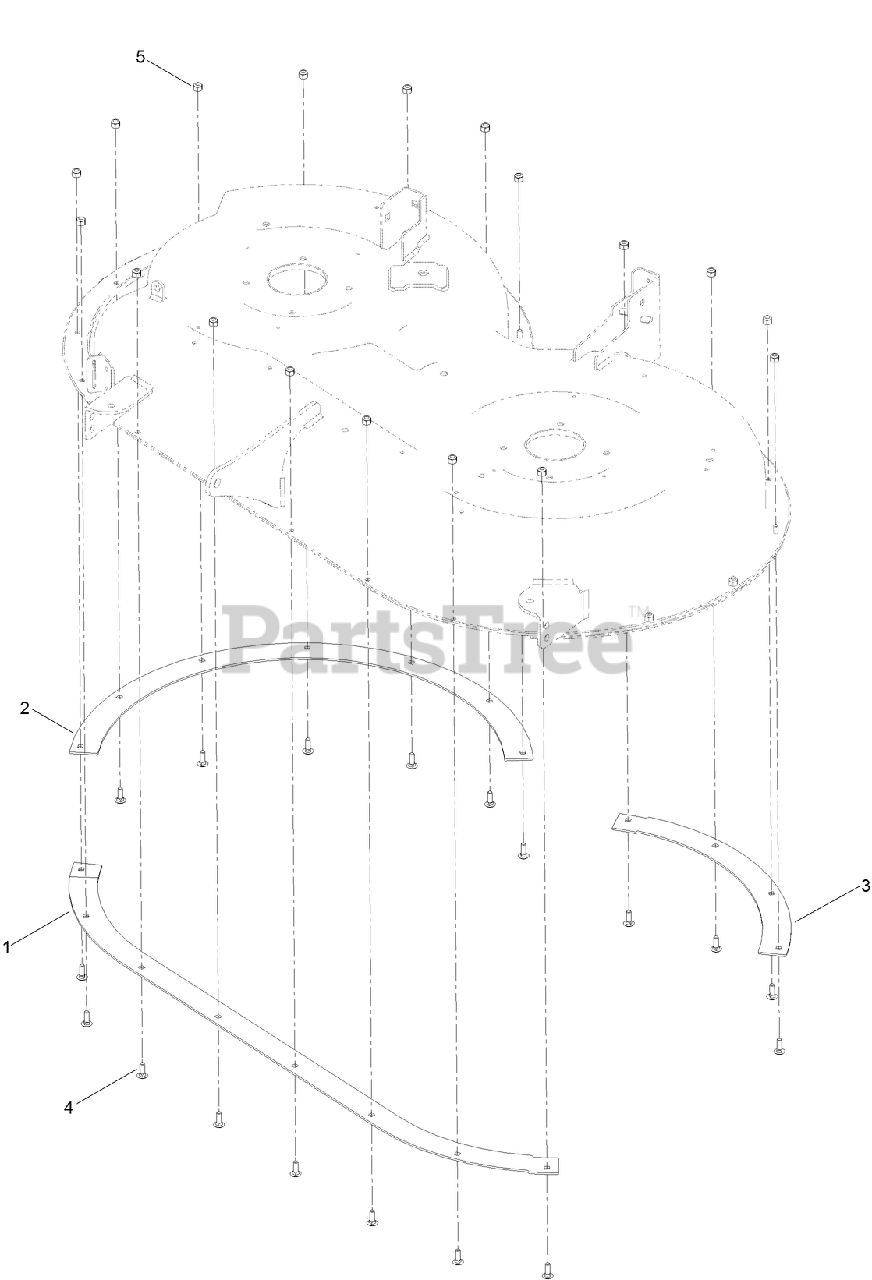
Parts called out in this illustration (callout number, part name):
1	BAFFLE-BLOWOUT, FRONT
2	BAFFLE-BLOWOUT, SIDE
3	BAFFLE-BLOWOUT, SIDE
4	BOLT-CARR
5	NUT-LOCK, NI
